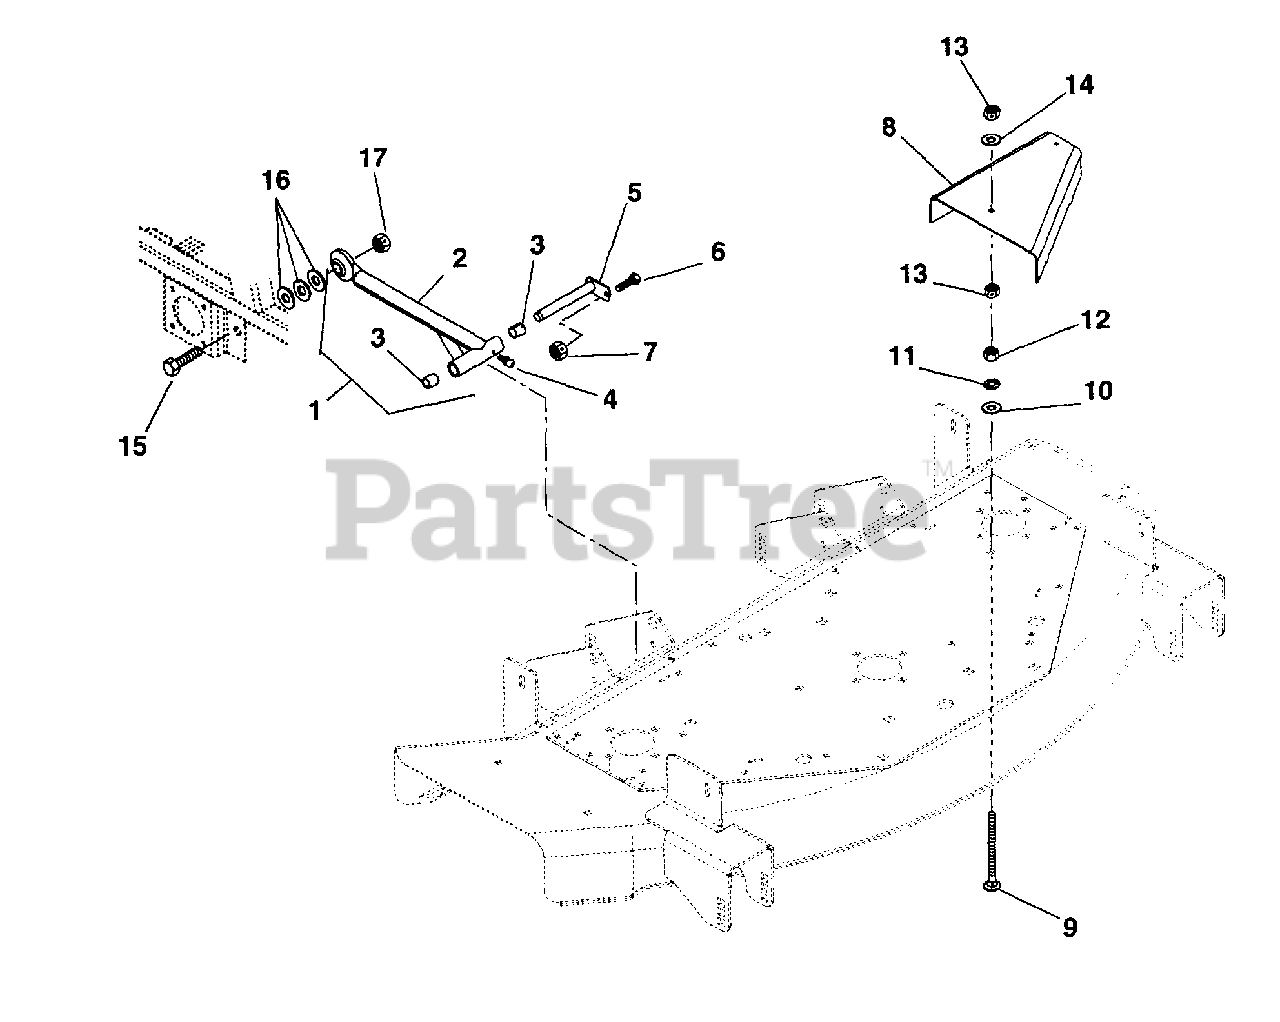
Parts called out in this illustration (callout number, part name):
1	ASSEMBLY, MOWER MOUNTING ARM
2	WELDMENT, MOWER MOUNTING ARM
3	BRG .75X.875X1.00
4	FTG-LUBE .25-28X.256 YWZC
5	WELDMENT, MOWER MTG. PIN
6	@BLT-HEX .38-16X.75 GR5 YWZC
7	@NUT-LK-CTR .38-16 YWZC
8	GUARD, PULLEY RH - ORANGE
9	@BLT-RDHDSQNK .31-18X3.50 G5YZ
10	@WSHR-FL-STL.344X.688X.065YWZC
11	@WSHR-LK .31X.078 REG YWZC
12	@NUT-HEX .31-18 YWZC
13	@NUT-LK-CTR .31-18 YWZC
14	@WSHR-FL-STL.438X1.00X.083 YWZ
15	BLT-HEX .875-9X2.75 GR5 YWZC
16	WSHR-FL-STL .890X1.500X.1196YZ
17	NUT-LK-CTR .875-9 YWZC
